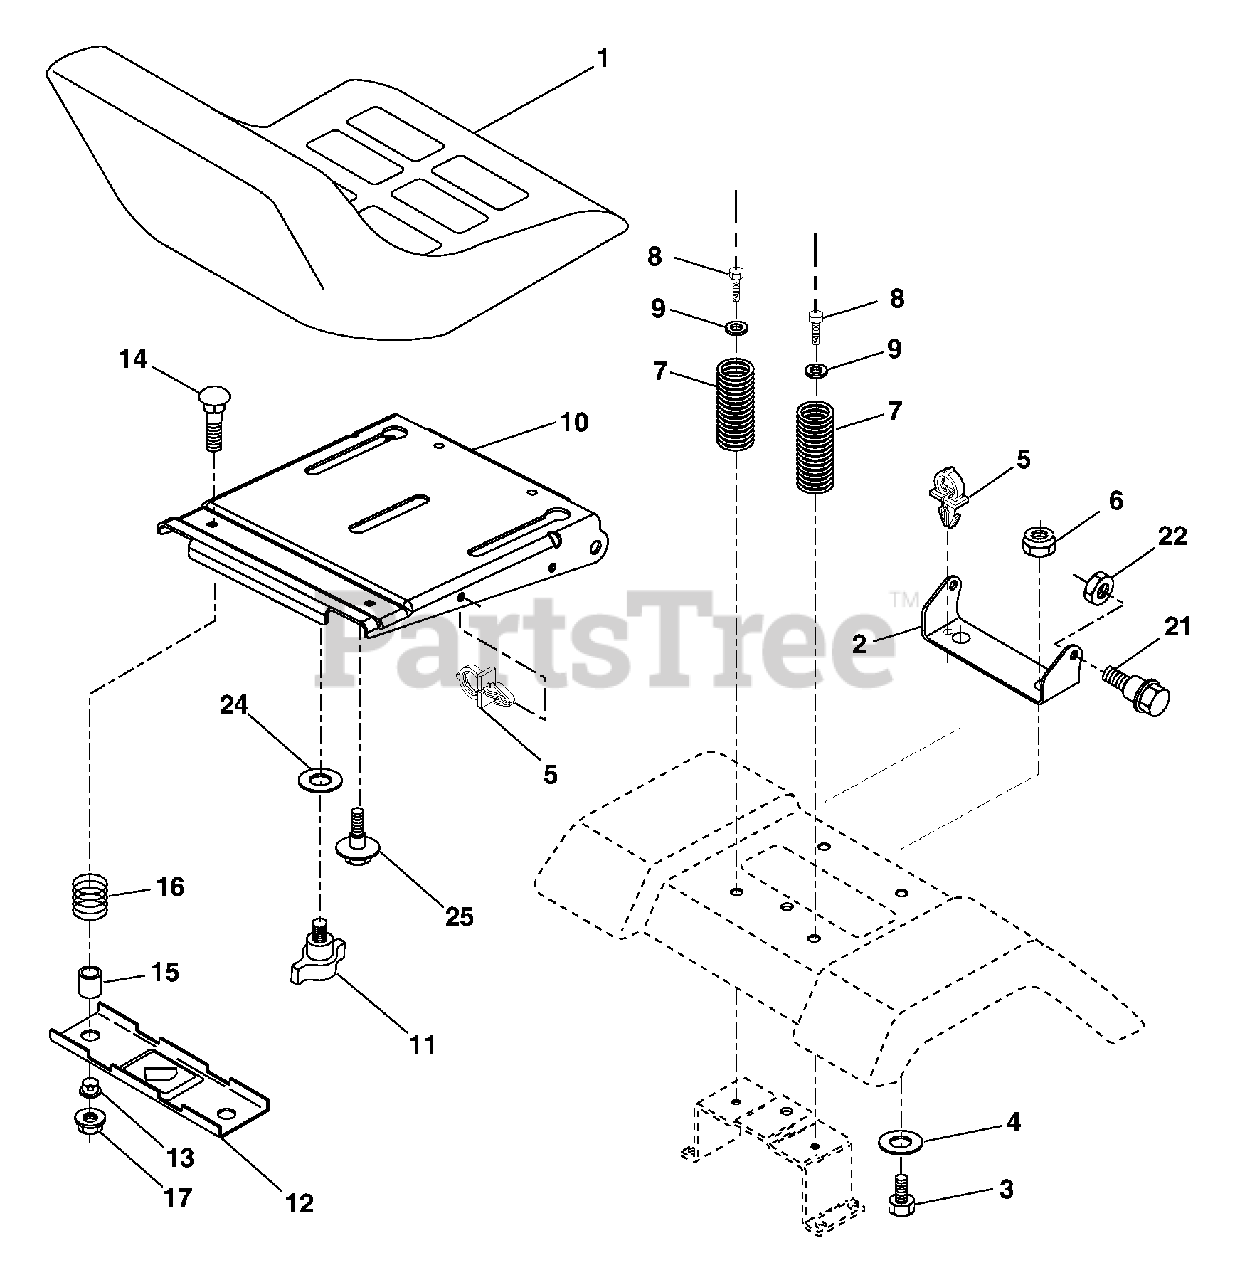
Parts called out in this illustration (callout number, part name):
1	Seat
2	Bracket Pivot Seat
3	Bolt Fin Hex 3/8-16 unc x 1
4	Washer Flat 13/32 x 1 x 10 Ga.
5	Clip Push-In
6	Nut Hex w/Ins. 3/8-16 unc
7	Spring Seat Cprsn 2 250 Blk Zi
8	Screw 3/8-16 x 1
9	Washer 13/32 x 1 x 14 Ga.
10	Pan Seat
11	Knob Seat Adj. Wingnut
12	Bracket Mounting Switch
13	Bushing Snap Blk Nyl 50 Id
14	Bolt Rdhd Sqnk 1/4-20 x 1-1/2
15	Spacer Split
16	Spring Cprsn
17	Nut Lock 1/4 Lge Flg Gr. 5 Zinc
21	Bolt Shoulder 5/16-18 unc
22	Nut Hex Lock W/Ins 5/16-18
24	Washer 17/32 x 1-3/16 x 12 Ga.
25	Bolt Shoulder 5/16-18 x 62
